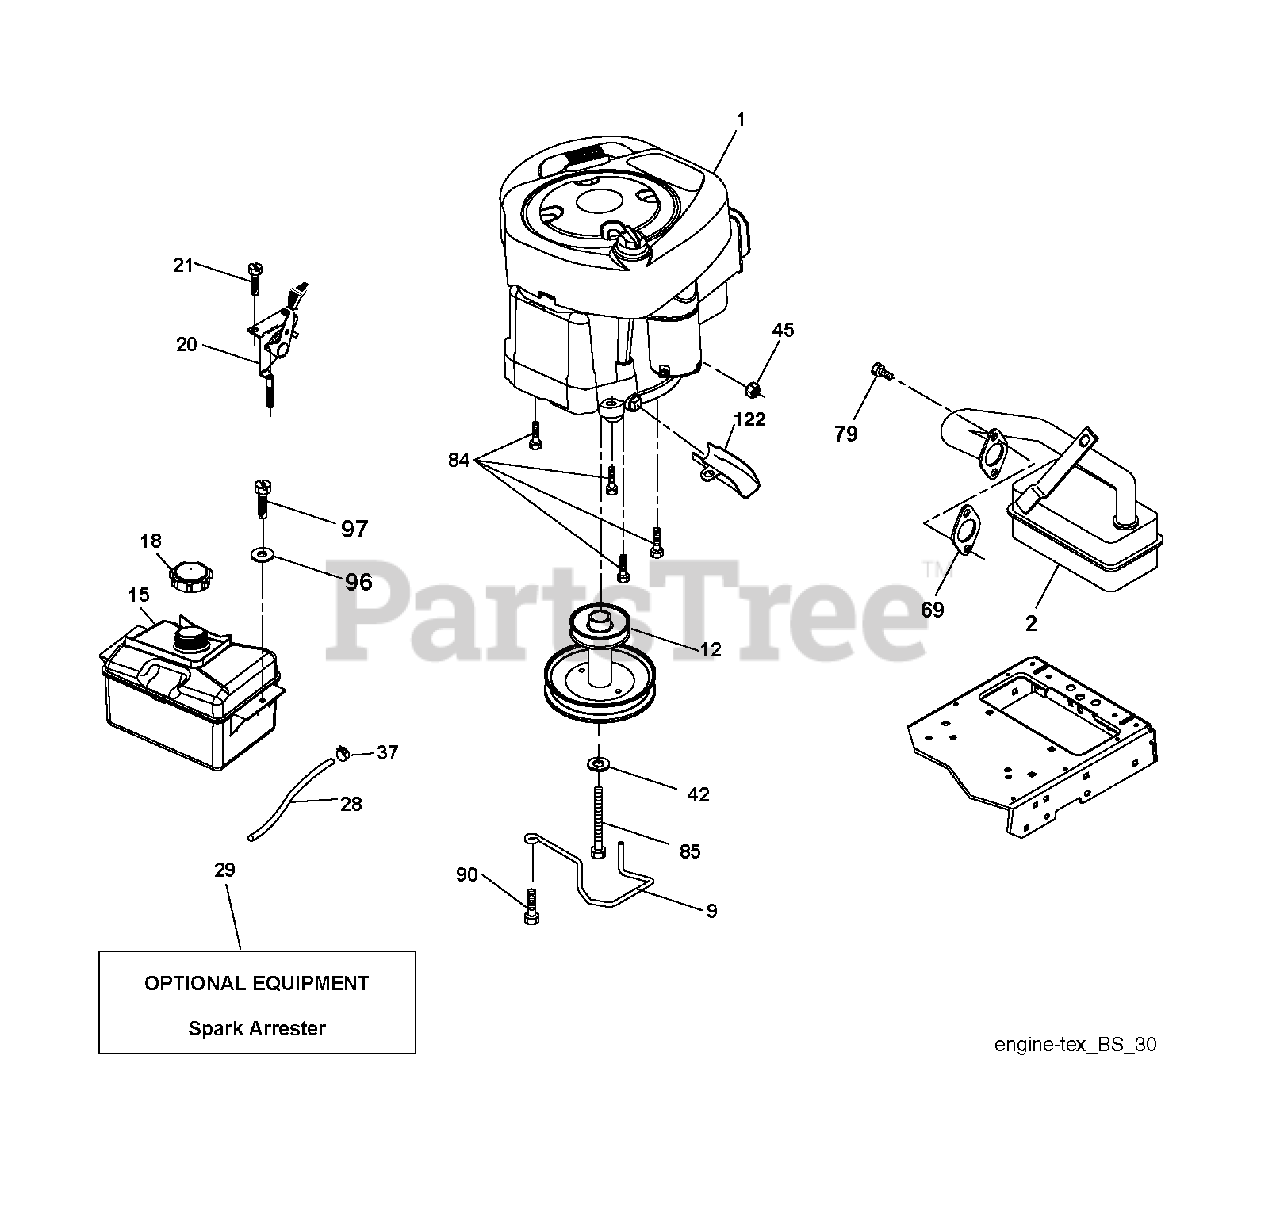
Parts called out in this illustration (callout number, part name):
2	MUFFLER.LT.BRIGGS.14HP.IC/OHV
9	KEEPER.BELT.ENGINE.4.2
12	PULLY ENGINE
15	RP TANK FUEL FRT 1.5 GAL
18	CAP ASM.FUEL.2.25"FR.
21	SCREW.#10 X 0.750.BOS (2 2)
28	LINE.FUEL.20
29	KIT.SPARK ARRESTOR(392390 B&S)
37	HOSE CLAMP
42	LOCKWASHER
45	NUT
79	SCREW.SOCKET HD.5/16-1
84	SCREW.3/8-16
85	BOLT HEX 7/16-20X4-1/4"
90	SCREW 3/8-16X1
97	SCREW HEXWSHR 1/4-20X3/4
122	EXTENSION DRAIN OIL
